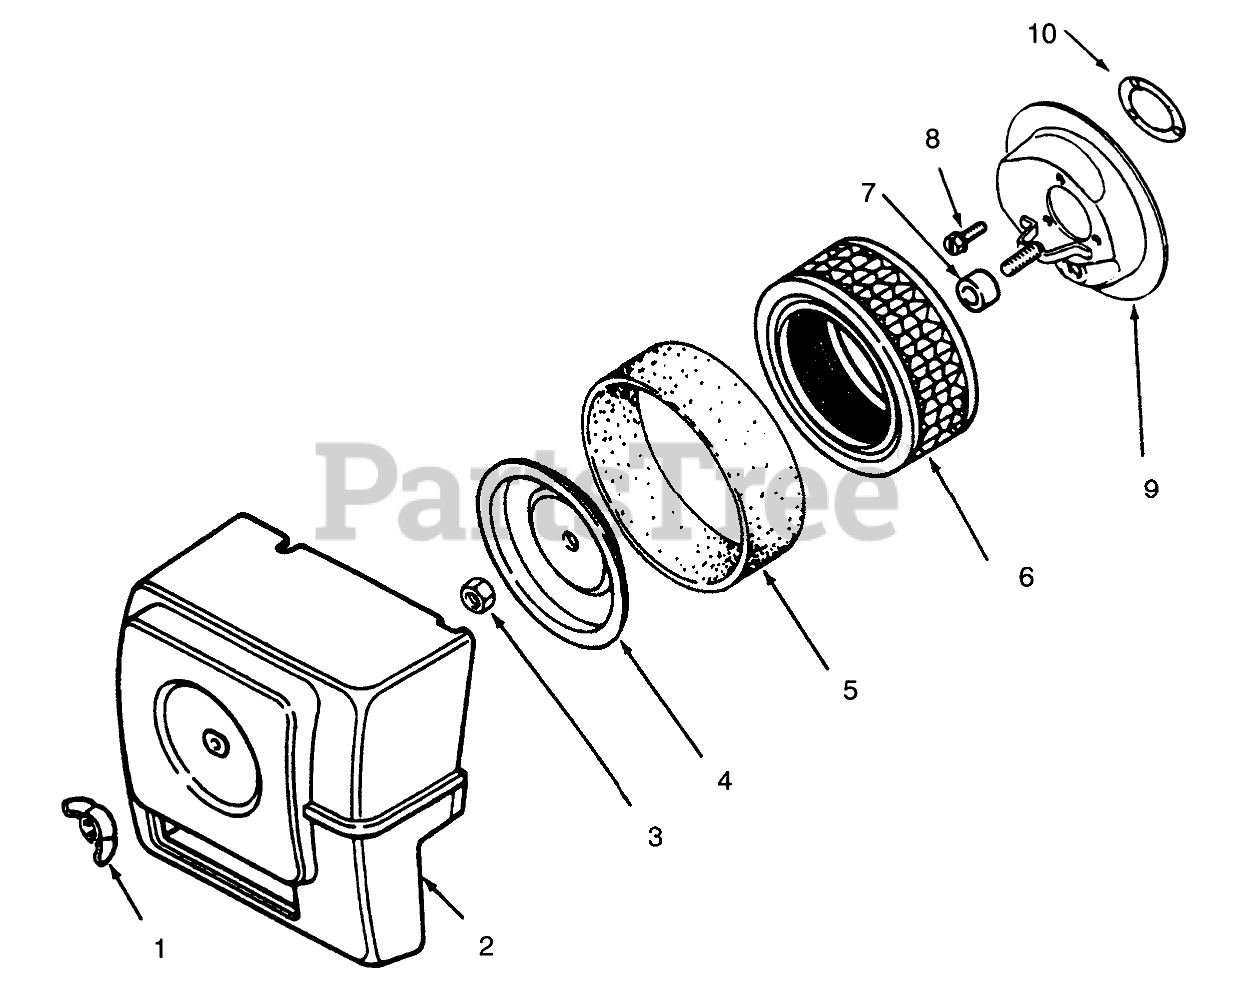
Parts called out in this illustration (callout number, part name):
1	Nut-Wing
2	Cover
4	Air Cleaner Element Cover
5	Element-Precleaner
6	Element
8	Screw
9	Base-AirCleaner
10	Gasket
